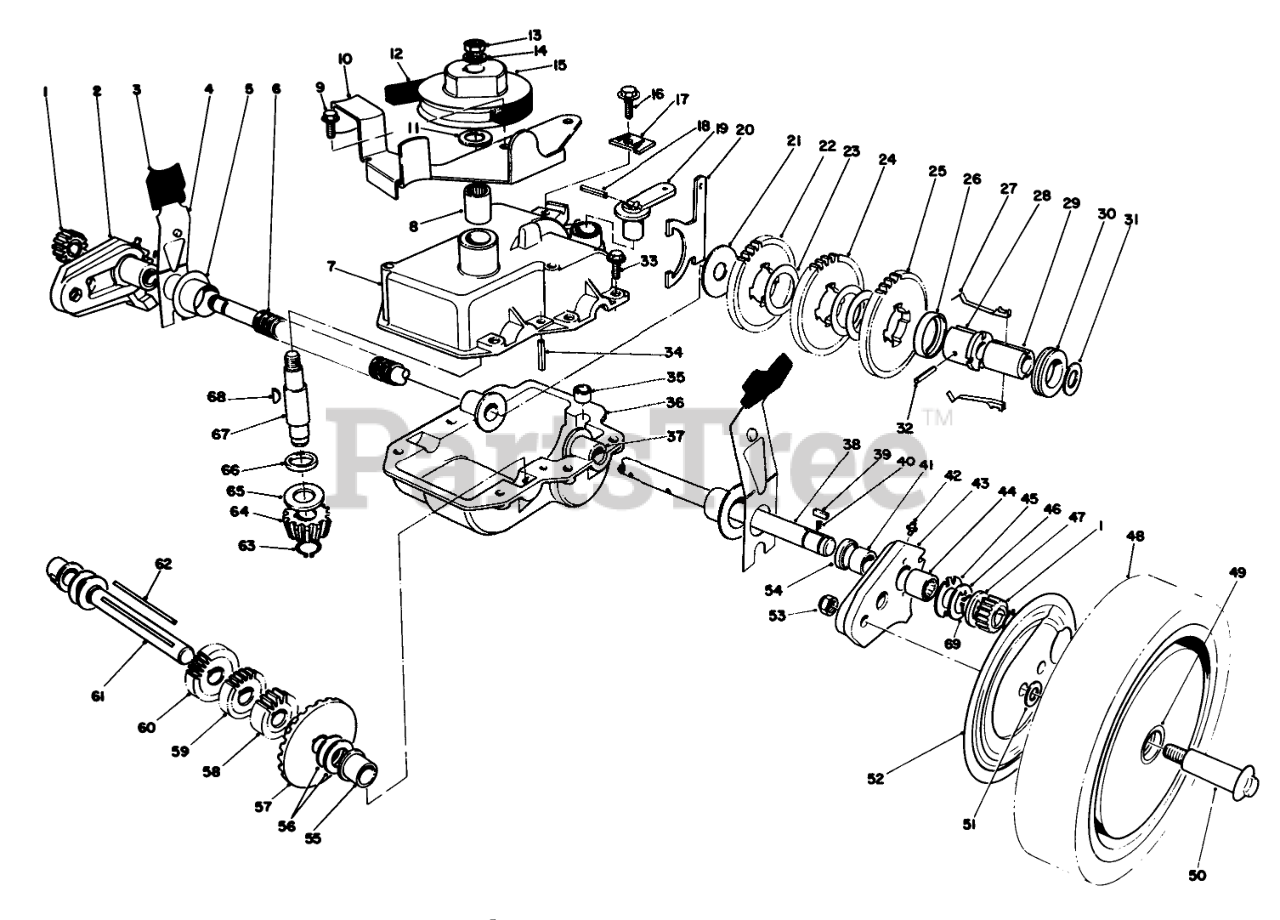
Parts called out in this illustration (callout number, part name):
1	GEAR-PINION
2	Pivot Arm Assembly-R.H. (Incl. Ref. #41, 42, 44 & 54)
3	KNOB-ARM
4	SPRING ARM ASM SP
5	CAP-END
6	CONDUIT-CONVOLUTED, SPLIT
7	Case-Upper
8	BEARING
9	SCREW
10	BELT GUIDE BRKTB
11	WASHER-THRUST
12	V-BELT
13	NUT-HEX
14	WASHER-FLAT
15	PULLEY
16	SCREW-HWHTF
17	Cable Clamp
18	PIN-COIL
19	LEVER-SHIFT
20	Shift Yoke
21	WASHER
22	GEAR-38T
23	WASHER
24	GEAR-42T
26	RETAINER-KEY
27	KEY-SHIFT
28	SLEEVE-GEAR
29	SLEEVE
30	COLLAR-SHIFT
31	WASHER-PLAIN
32	PIN-SPRING
33	SCREW-HWHTF
34	ROLL PIN 3/16 X 1 IN
35	BUSHING-YOKE
36	LOWER GEAR CASE CAST
37	Bushing-Output Shaft
38	Output Shaft
39	KEY RECTANGULAR
40	SPRING-COMPRESSION
41	BUSHING
42	FITTING-GREASE
43	Pivot Arm Assembly-L.H. (Incl. Ref. #41, 42, 44 & 54)
44	BEARING-ROLLER
45	INNER THRUST WASHER
46	WASHER-THRUST, OUTER
47	WASHER-THRUST, OUTER
48	Wheel, Tire & Gear Assembly (Incl. Ref. #49)
49	BUSHING
50	BOLT-WHEEL
51	WASHER
52	WHEEL COVER
53	Nut
54	SEAL-OIL
55	BUSHING
56	WASHER-THRUST
57	BEVEL GEAR
58	GEAR-12T
59	GEAR-14T
60	GEAR-18T
61	INTERMEDIATE SHAFT
63	RING-RETAINING
64	PINION-BEVEL
65	WASHER-THRUST
67	INPUT SHAFT
68	KEY-WOODRUFF
69	RING-RETAINING
